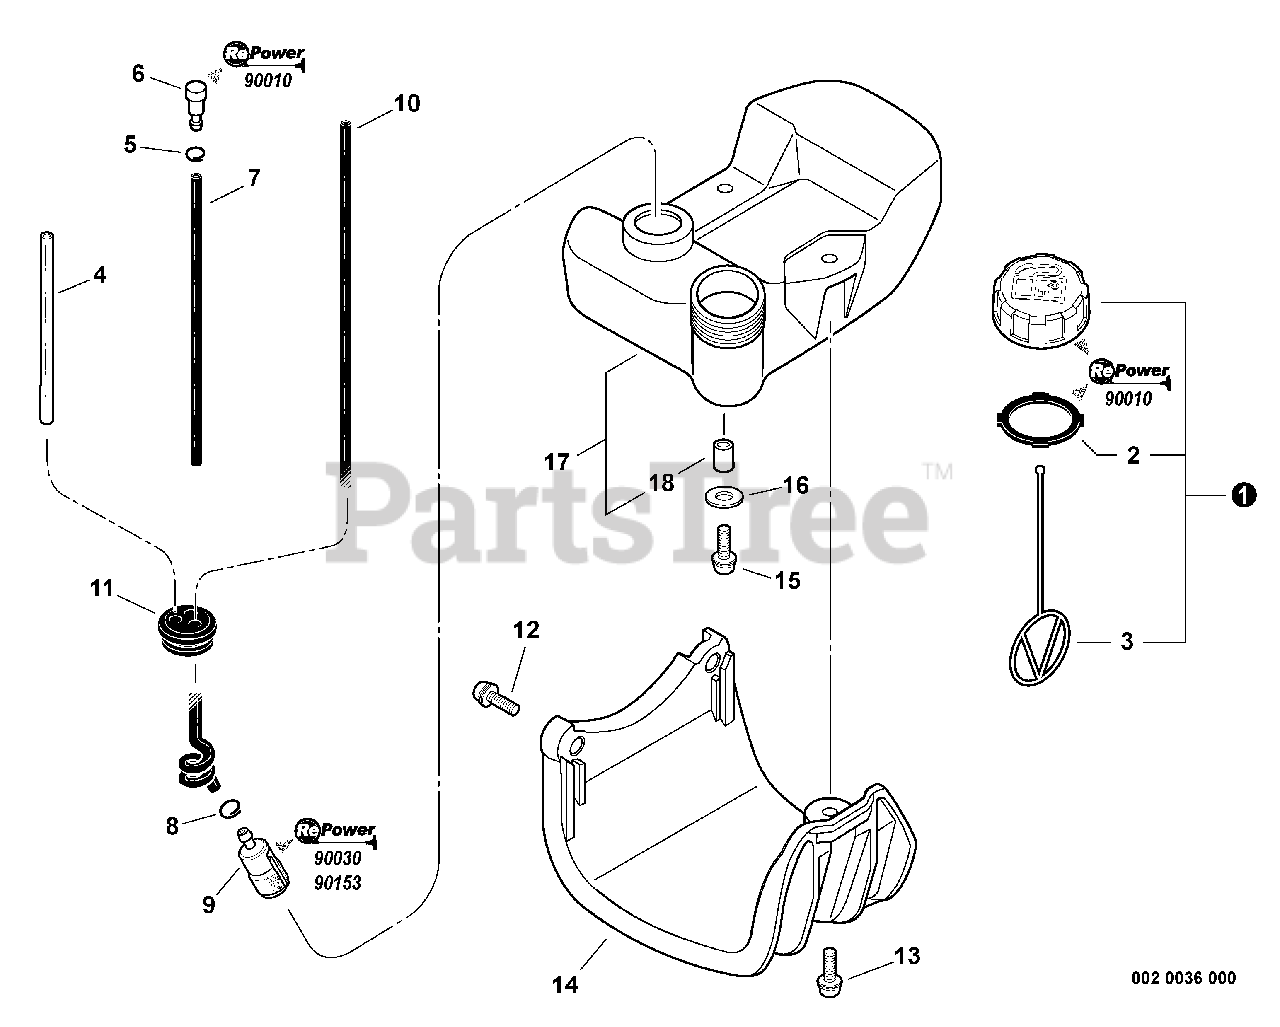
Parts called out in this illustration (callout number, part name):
1	CAP ASSY - ORANGE
2	GASKET, CAP
3	CONNECTOR, CAP
4	PIPE - 3X6X80 -- CLEAR
5	CLIP - 6.5
6	VENT, FUEL TANK
7	PIPE - 3X6X115 -- BLACK
8	CLIP - 6.5
9	FILTER, FUEL
10	PIPE, FUEL - SPIRAL
11	GROMMET
12	SCREW - 5X22
13	SCREW - 5X20
14	GUARD, FUEL TANK
15	SCREW - 5X16
16	WASHER - 5
17	FUEL TANK ASSY
19	Repower CAP AND VENT KIT
20	RePower FILTER KIT
21	RePower TUNE-UP KIT
